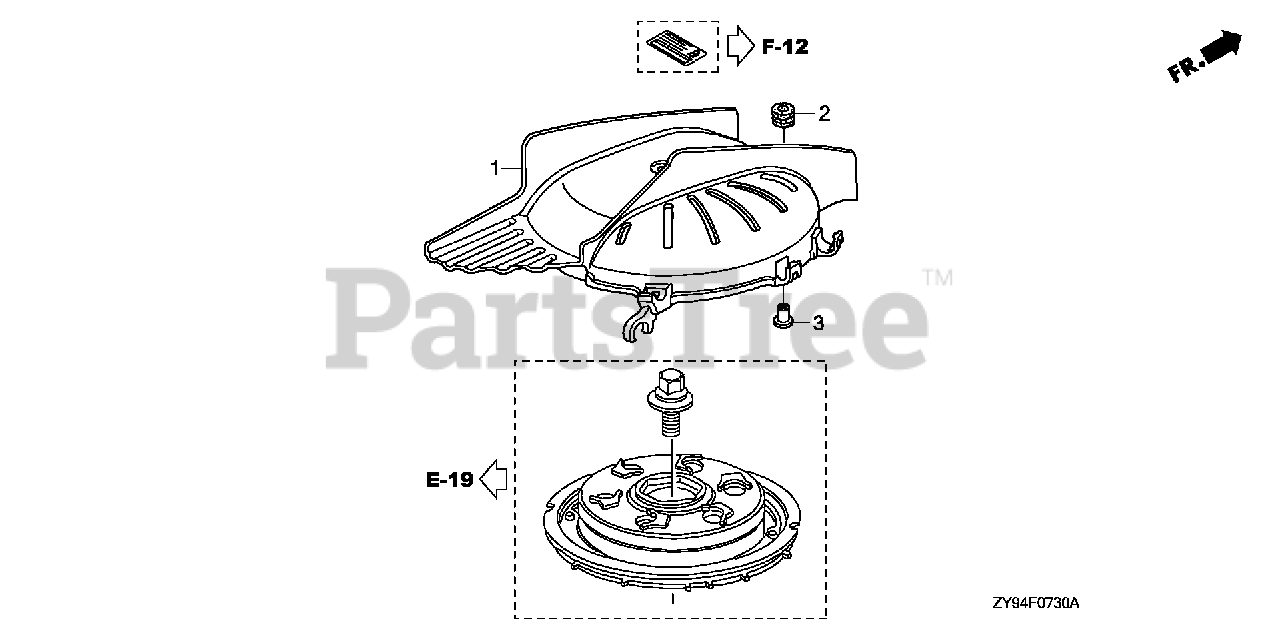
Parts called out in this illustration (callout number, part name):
1	COVER ASSY., ALTERNATOR
2	GROMMET, CASE (LOWER)
3	COLLAR, MODULE IGNITION CONTROL CASE (CDI)
